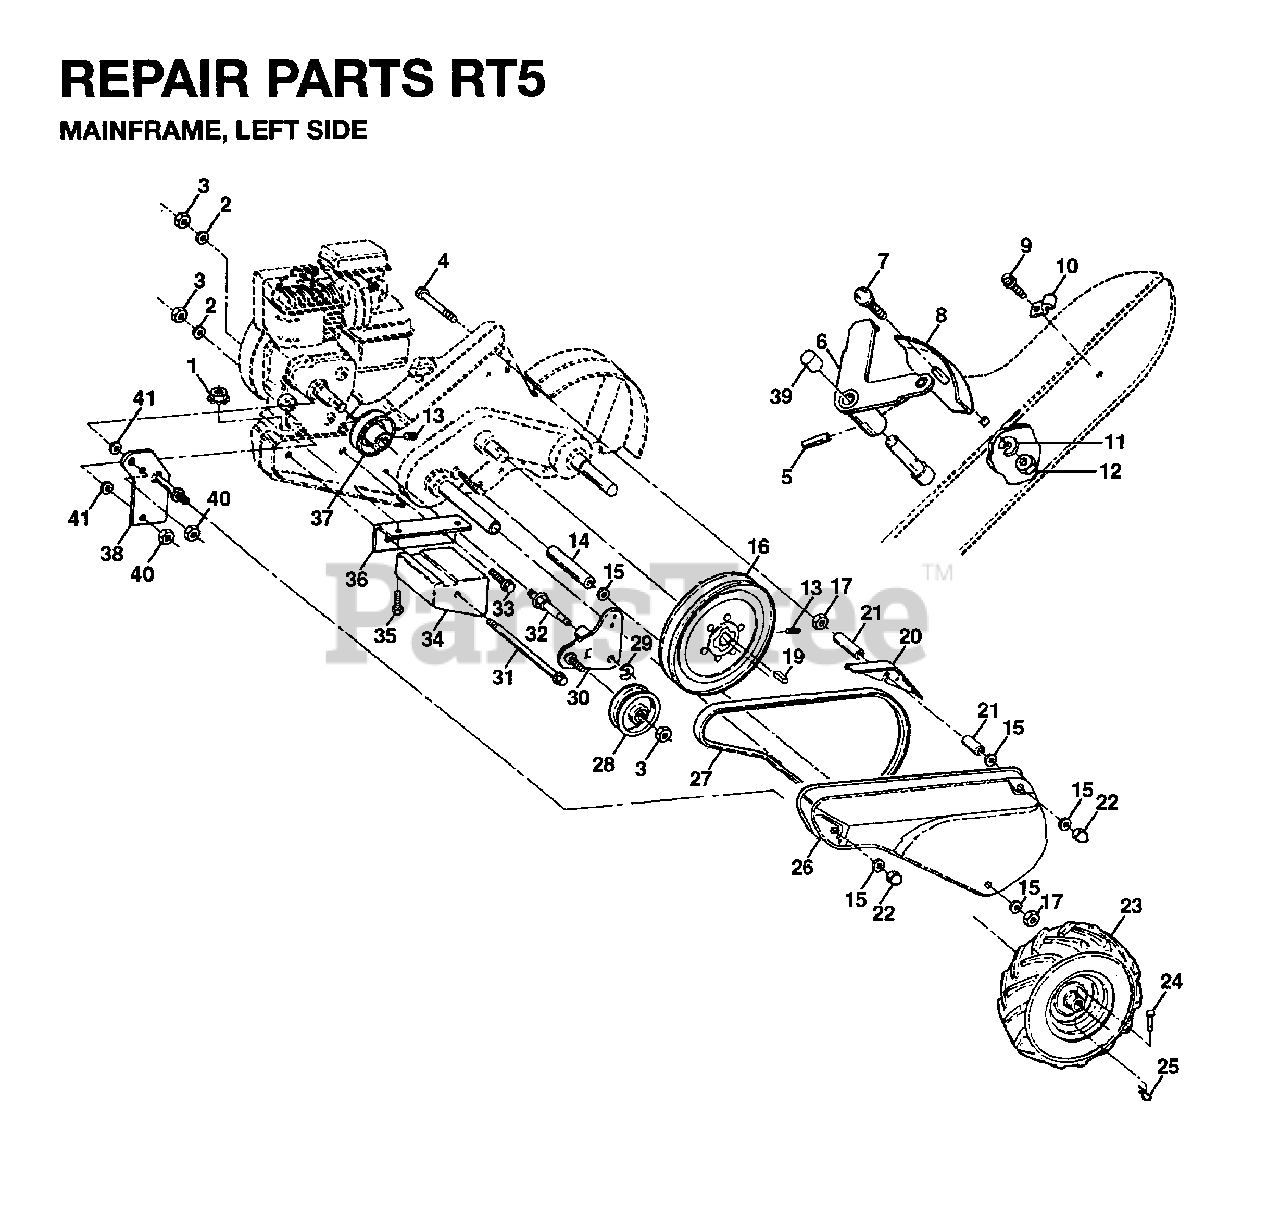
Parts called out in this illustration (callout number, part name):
1	LOCKNUT
2	WASHER, LOCK 3/8
3	NUT.HEX.3/8-16UNC
5	DRIVE PIN
6	LEVER ASM CRT
10	CONDUIT CLIP T
11	LOCKWASHER
12	NUT
13	SET SCREW **
14	SPACER
15	WASHER - 15X7.3X1.6
16	SHEAVE 10" CRT
17	NUT
18	SPACER CRT
20	GUARD CRT
21	SPACER SPLIT
24	RIVET,DRILLED
25	RETAINER M
27	V-BELT
28	PULLEY-IDLER TI
29	KLIP RING
30	BRACKET ASSY TI
31	BOLT.FIN.HEX.3/8-16UNC
32	SHIFT ARM CRT
33	BOLT
34	COUNTERWEIGHT.LH.CRT
35	HEX BOLT
36	BRACKET LH CRT
37	ENGINE PULLEY
39	CAP.PLUNGER.BLACK
40	NUT
5320651-39	VALVE STEM LT
5321289-52	WHEEL.8X2-3/4.TILLER /RIM ONLY
